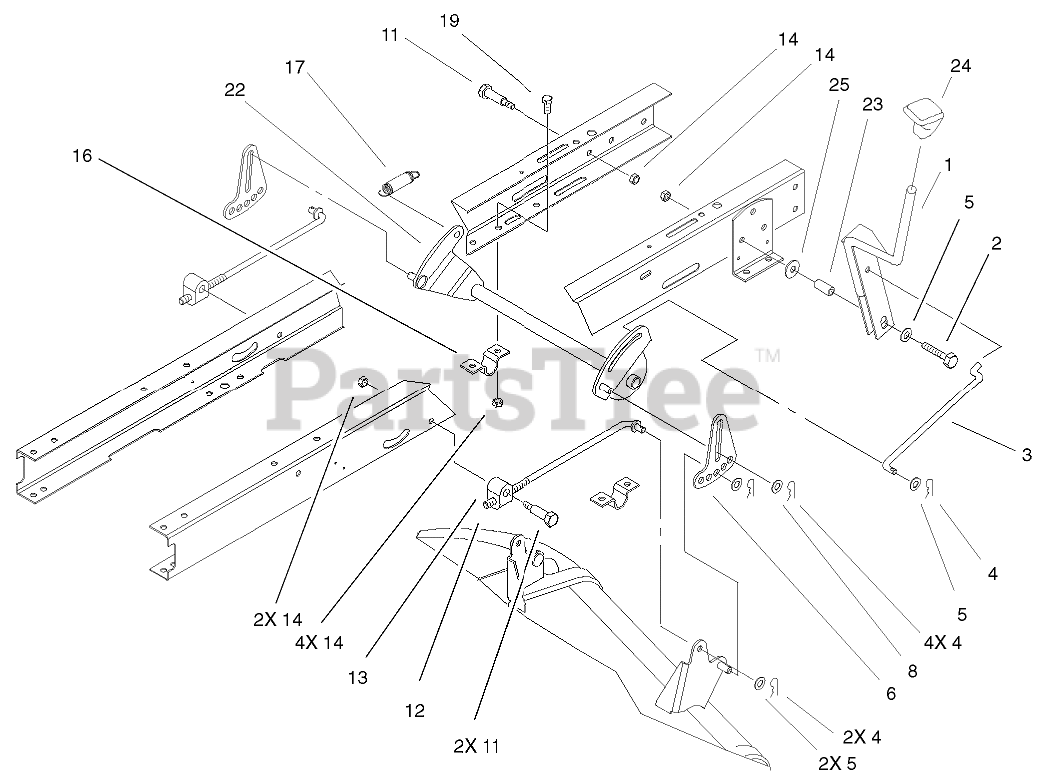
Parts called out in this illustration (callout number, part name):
1	HOC LEVER ASM
2	SCREW-HH
3	LINK-HOC
4	PIN-COTTER
5	WASHER-FLAT
6	LINK-ADJUSTING, HOC
8	WASHER-HARDENED
11	SCREW-SHOULDER, HH
12	ROD-HANGER, REAR
13	TRUNNION-HOC
14	NUT-LOCK, NI
16	CLAMP-PIVOT, HOC
17	SPRING-EXTENSION
19	SCREW-HH
22	PIVOT ASM
23	SPACER
24	KNOB-SHIFT
25	WASHER-PIVOT
